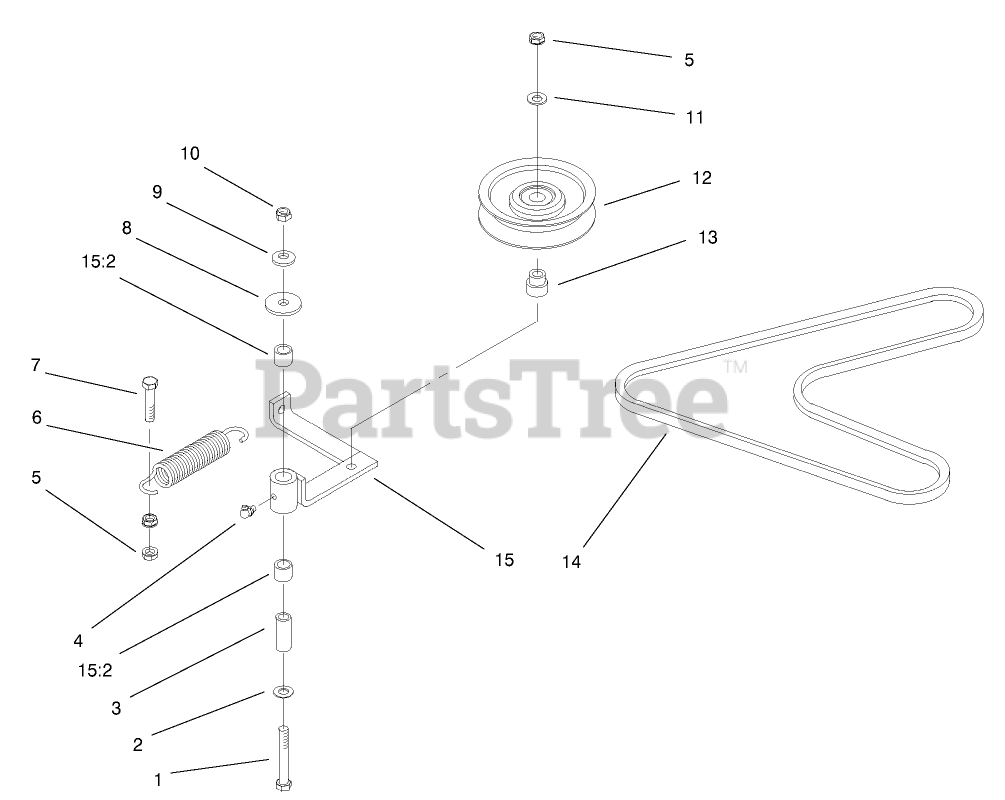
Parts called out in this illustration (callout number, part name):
1	SCREW-HH
2	WASHER-FLAT
3	BUSHING
4	FITTING-GREASE, 90 DEG
5	NUT-HHF, WHIZ
6	Spring-Extension
7	SCREW-HH
8	WASHER
9	WASHER-BELLEVILLE
10	NUT-LOCK, NI
11	WASHER-FLAT
12	PULLEY-IDLER
13	BUSHING-IDLER
14	BELT-PUMP
15	ARM-IDLER
15:2	SLEEVE-BEARING
